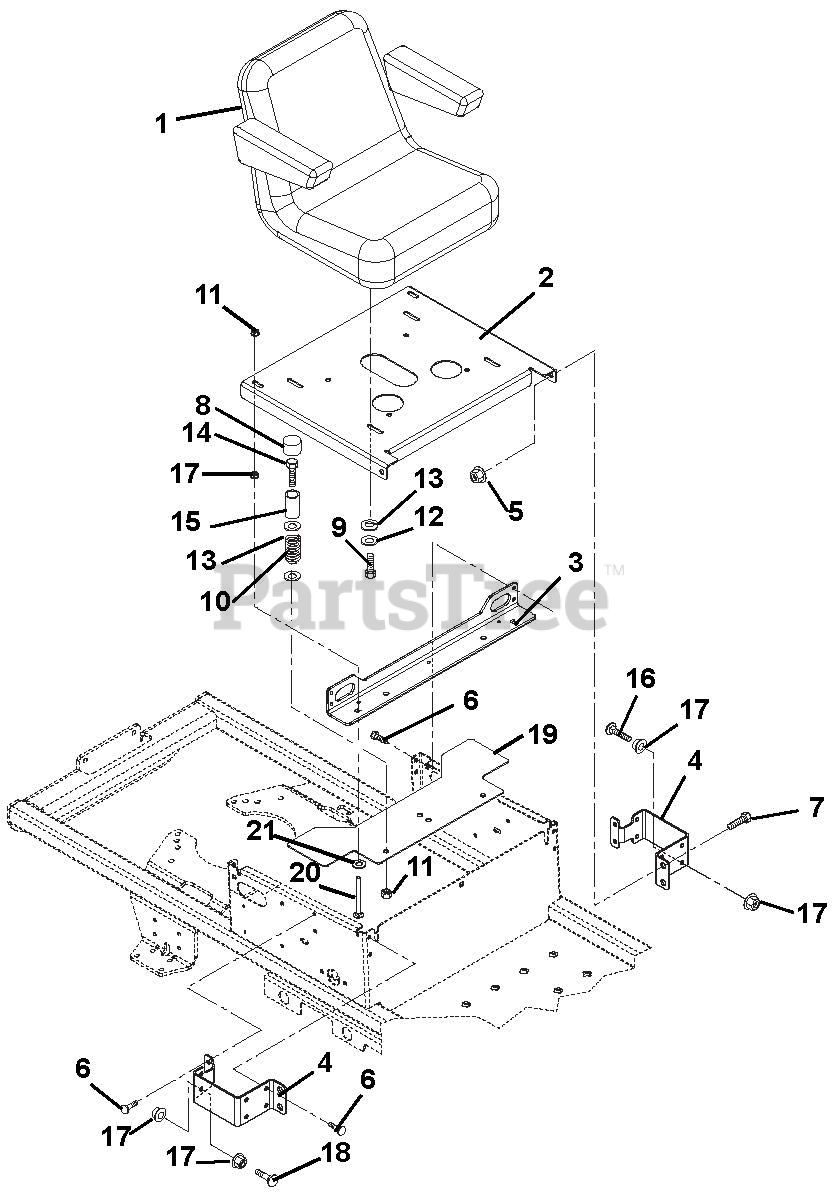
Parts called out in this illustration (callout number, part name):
1	SEAT,V-2505 MICHIGAN W/ARM
2	SEAT PLATE
3	BKT,SEAT SPRING
4	BKT,SEAT PIVOT
5	@NUT-LK-TOP-FLG .38-16 YWZC
6	@SCR-TAP .31-18X.50 HWH TR YWZ
7	BOLT-SHLDR .375-16X.150
8	HUB CAP
9	@BLT-HEX .31-18X1.00 GR5 YWZC
10	SG. COMP 2.9L X 2.02OD 200LB
11	@NUT-LK-NYL-FLG .31-18 YWZC
12	@WSHR-LK .31X.078 REG YWZC
13	WSHR-FL-STL .328X.87X.179 YWZC
14	@BLT-HEX .31-18X2.75 GR5 YWZC
15	BSHG-SLV .334 X .502 X 1.437
16	@BLT-RDHDSQNK .31-18X2.50 G5YZ
17	@NUT-SPNLK-FLG .312-18 YWZC
18	@BLT-RDHDSQNK .31-18X1.75 G5YZ
19	GUARD,CE FINGER
20	@BLT-RDHDSQNK .31-18X3.50 G5YZ
21	WSHR-FL-STL .505X1.00X.062YWZC
